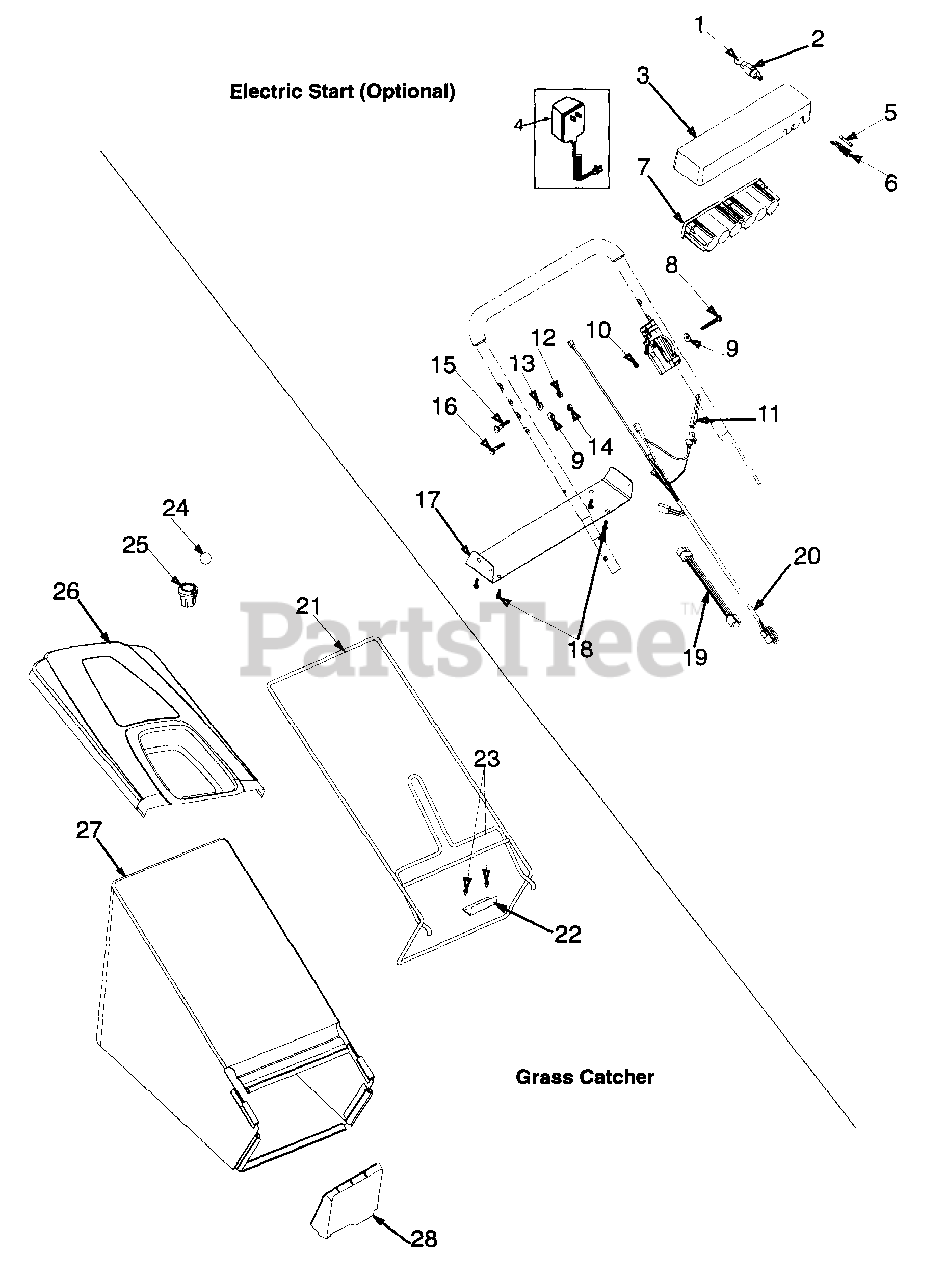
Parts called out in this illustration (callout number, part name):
1	Ignition Key
2	Key Switch
3	Battery Tray
4	Battery Charger
5	Fuse 7.5 Amp
6	Fuse Holder
7	Battery 12V
8	Hex Screw: 1/4-20: 2.0
9	Bell Washer .265 x .75 x .062
10	Special Hex Nut 5/16-18
11	Plug
12	Nut 5/16-18
13	Bell Wash .340 ID x .872 OD
14	Hex Nut 1/4-20
15	Carriage Bolt 5/16-18 x 1
16	Carriage Screw
19	Harness Extension
20	Harness
24	Flow Ball
25	Indicator Flow Assembly
26	Hard Top Cover w/Logo
27	Grass Bag
